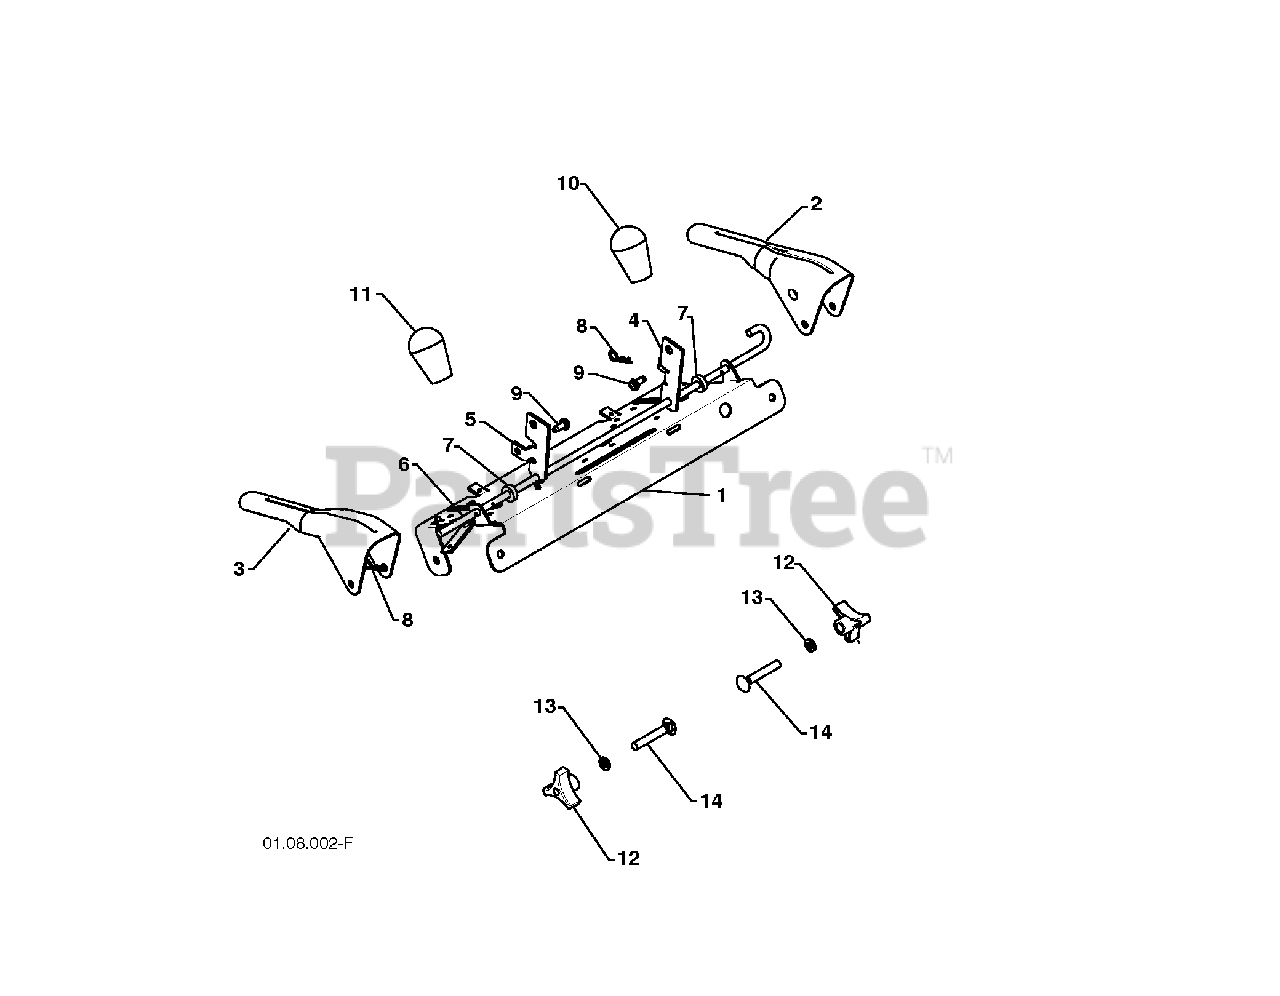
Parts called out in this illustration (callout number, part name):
1	PANEL.CONTROL
2	LEVER.CONTROL.LH.431
3	LEVER.CONTROL.RH.431
4	ARM.TRACTION.ROD.YZ
6	BAIL.CONTROL.INTERLOCK
7	SPACER.CONTROL.LEVER
8	SPRING RETAINER
9	SCREW 14-20 X 5/8
10	KNOB LEVER, BLACK
11	RED KNOB SHIFTER
12	KNOB.HANDLE.3/8.TRI-POINT.BLAC
14	BOLT 3/8-16 X 2-1/4
